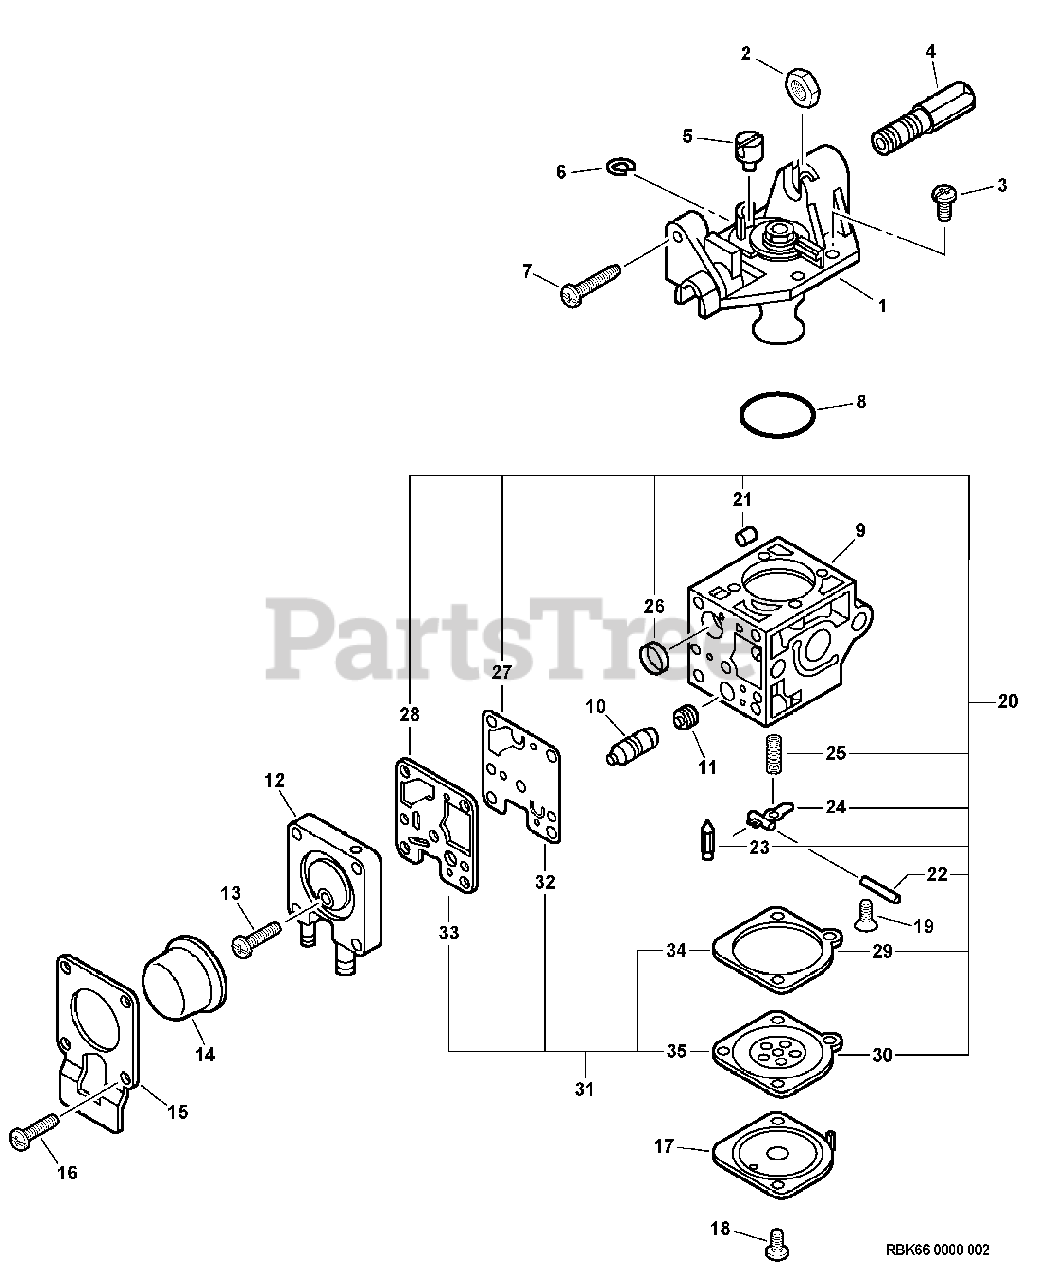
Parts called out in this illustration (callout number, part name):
1	COVER ASSY, ROTOR
4	ADJUSTER, THROTTLE CABLE
7	SCREW, IDLE ADJUST
9	BODY, CARBURETOR
10	PLUG KIT
11	JET, MAIN
12	BASE, PURGE
14	BULB, PURGE
15	RETAINER, PURGE BULB
16	SCREW
17	COVER, METERING DIAPHRAGM
20	REBUILD KIT
21	GUIDE, ROLLER
22	PIN, METERING LEVER
23	VALVE, INLET NEEDLE
24	LEVER, METERING
25	SPRING, METERING LEVER
26	STRAINER
27	DIAPHRAGM, PUMP
28	GASKET, PUMP
29	GASKET, DIAPHRAGM
30	DIAPHRAGM, METERING
31	GASKET / DIAPHRAGM KIT
32	DIAPHRAGM, PUMP
33	GASKET, PUMP
34	GASKET, DIAPHRAGM
35	DIAPHRAGM, METERING
